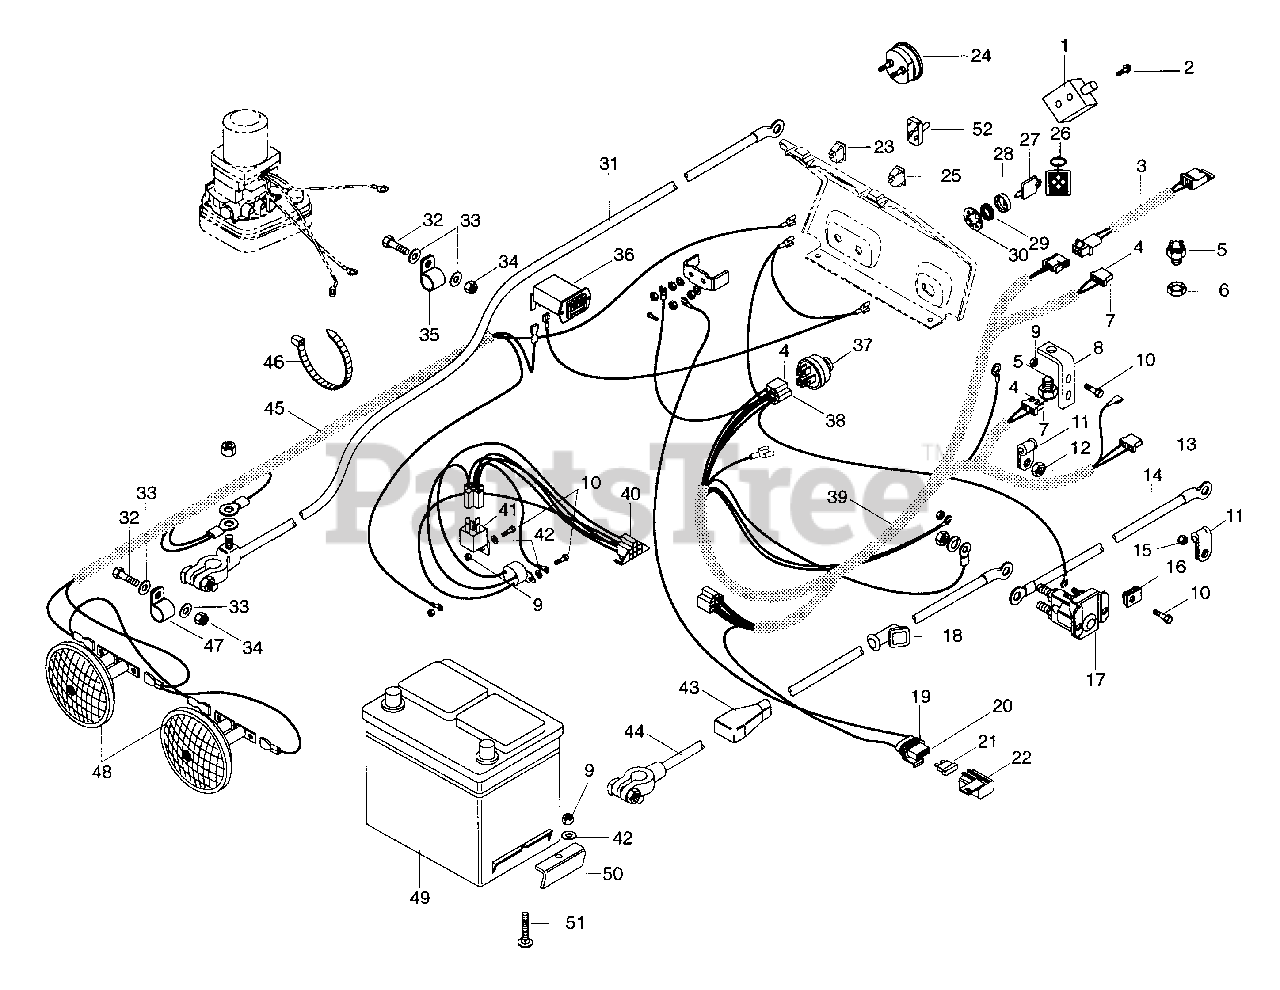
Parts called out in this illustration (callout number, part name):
1	Switch, Double Pole N.O./N.O.
2	Screw-Tapping 12-24 x .50
3	Harness, Wiring Seat Switch
4	Terminal
5	Switch, Neutral Start N.O.
6	Nut-Stamped .56-18
7	Connector, 2 Wire Switch
8	Bracket, Switch
9	Nut-Locking-Nylon .250-20 Grade 2
10	Bolt-Hex .25-20 x .75 Grade 2
11	Clamp
12	Nut-Locking-Center .625-10 Grade 2
13	Connector
14	Cable Starter
15	Nut-Locking-Nylon .375-16 Grade 2
16	Nut-Speed .25-20
17	Solenoid
18	Boot, Insulator
19	Assembly, Connector Weather Tight
20	Terminal, For 14-16 Gauge Wire
21	Fuse, 25 AMP
22	Cover
23	Light, Cover
24	Gauge, Indicator
25	Switch, Light
26	Key Chain
27	Ignition Switch Key
28	Cap-Ignition Switch
29	Nut-Panel .562-24
29	Nut-Panel .625-32
30	Washer-Lock Internal .563 x .040
30	Washer-Lock Internal .625 x .045
31	Cable, Negative battery
32	Bolt-Hex .31-18 x 1.00 Grade 5
33	Washer-Flat-Steel .344 x .688 x .065
34	Nut-Locking-Nylon .312-18 Grade 2
35	Clamp, Steel 1.0
36	Hour Meter
37	Ignition Switch
37	Switch, Key
38	Connector
39	Harness, Wiring
40	Module, time Delay
41	Relay
42	Washer-Flat-Steel .281 x .62 x .065
43	Cover, Battery Terminal
44	Cable, battery to Magneto switch
45	Harness, Wiring Ground & Lights
46	Tie, Cable
47	Cable Clamp
48	Head Light
49	Battery, 12Volt
50	Clamp
51	Bolt, Round Head Square Neck .25-20 x 1.75
52	Switch Assembly
